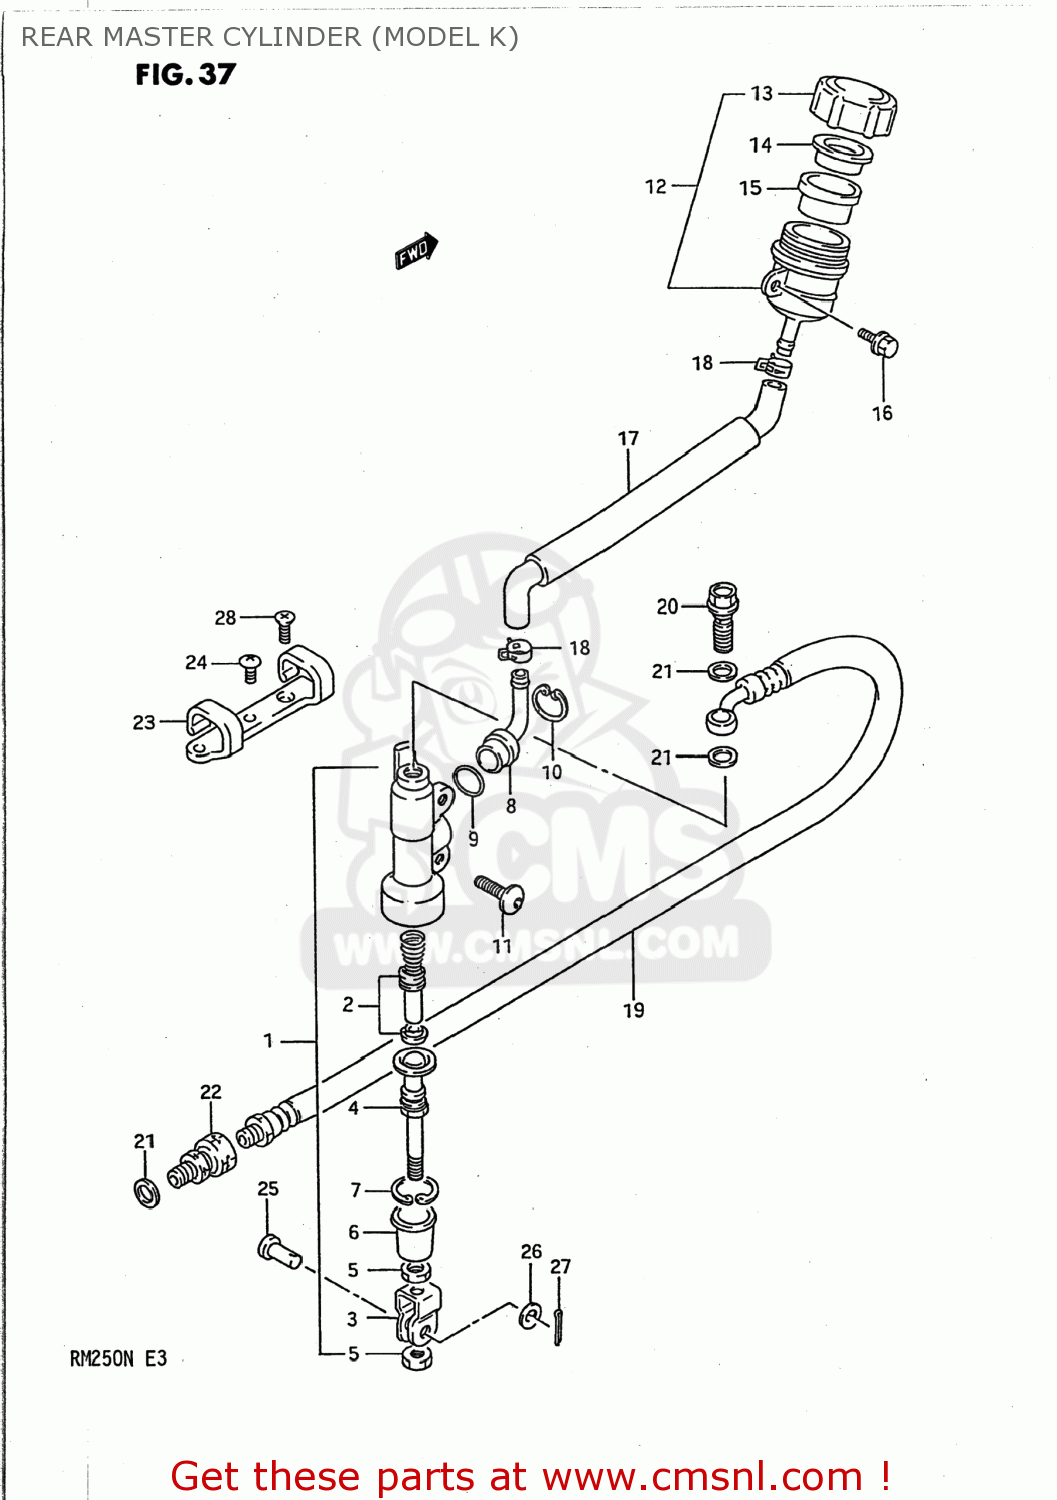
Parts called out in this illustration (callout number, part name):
1	CYLINDER ASSEMBLY,REAR MASTER
2	PISTON/CUP SET
3	YOKE
4	ROD,PUSH
5	NUT
6	BOOT
7	CIRCLIP
8	CONNECTOR
9	O RING
10	CIRCLIP
11	BOLT(6X18)
12	TANK ASSEMBLY,RESERVOIR
13	CAP
14	PLATE
15	DIAPHRAGM
16	BOLT
17	HOSE,RESERVOIR
18	CLAMP,RESERVOIR HOSE
19	HOSE,REAR BRAKE
20	BOLT UNION
21	WASHER(10X15X1.5)
22	ADAPTOR,BRAKE HOSE
23	GUIDE,REAR BRAKE HOSE
24	SCREW(5X10)
25	PIN(8X20)
26	WASHER(8.5X13X1.6)
27	PIN
28	SCREW(5X10)
